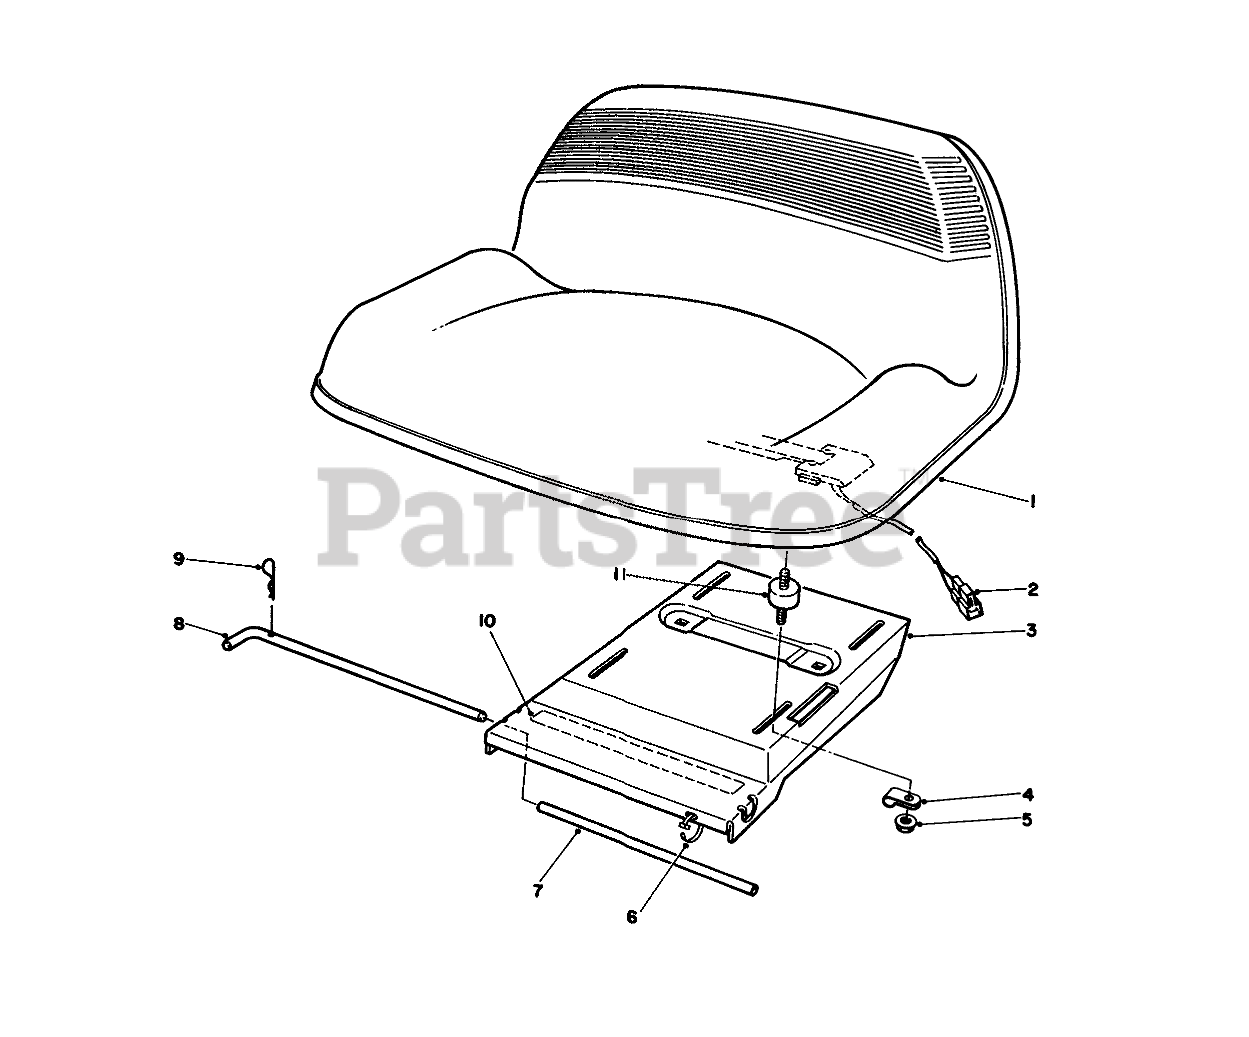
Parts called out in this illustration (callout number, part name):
1	Seat
2	SWITCH-SEAT
3	Base-Seat
4	CLAMP
5	NUT-HF
6	TIE-CABLE
7	TUBE-SEAT
8	ROD-SEAT BASE
9	PIN-COTTER
10	DECAL
11	ISOLATER-SEAT
